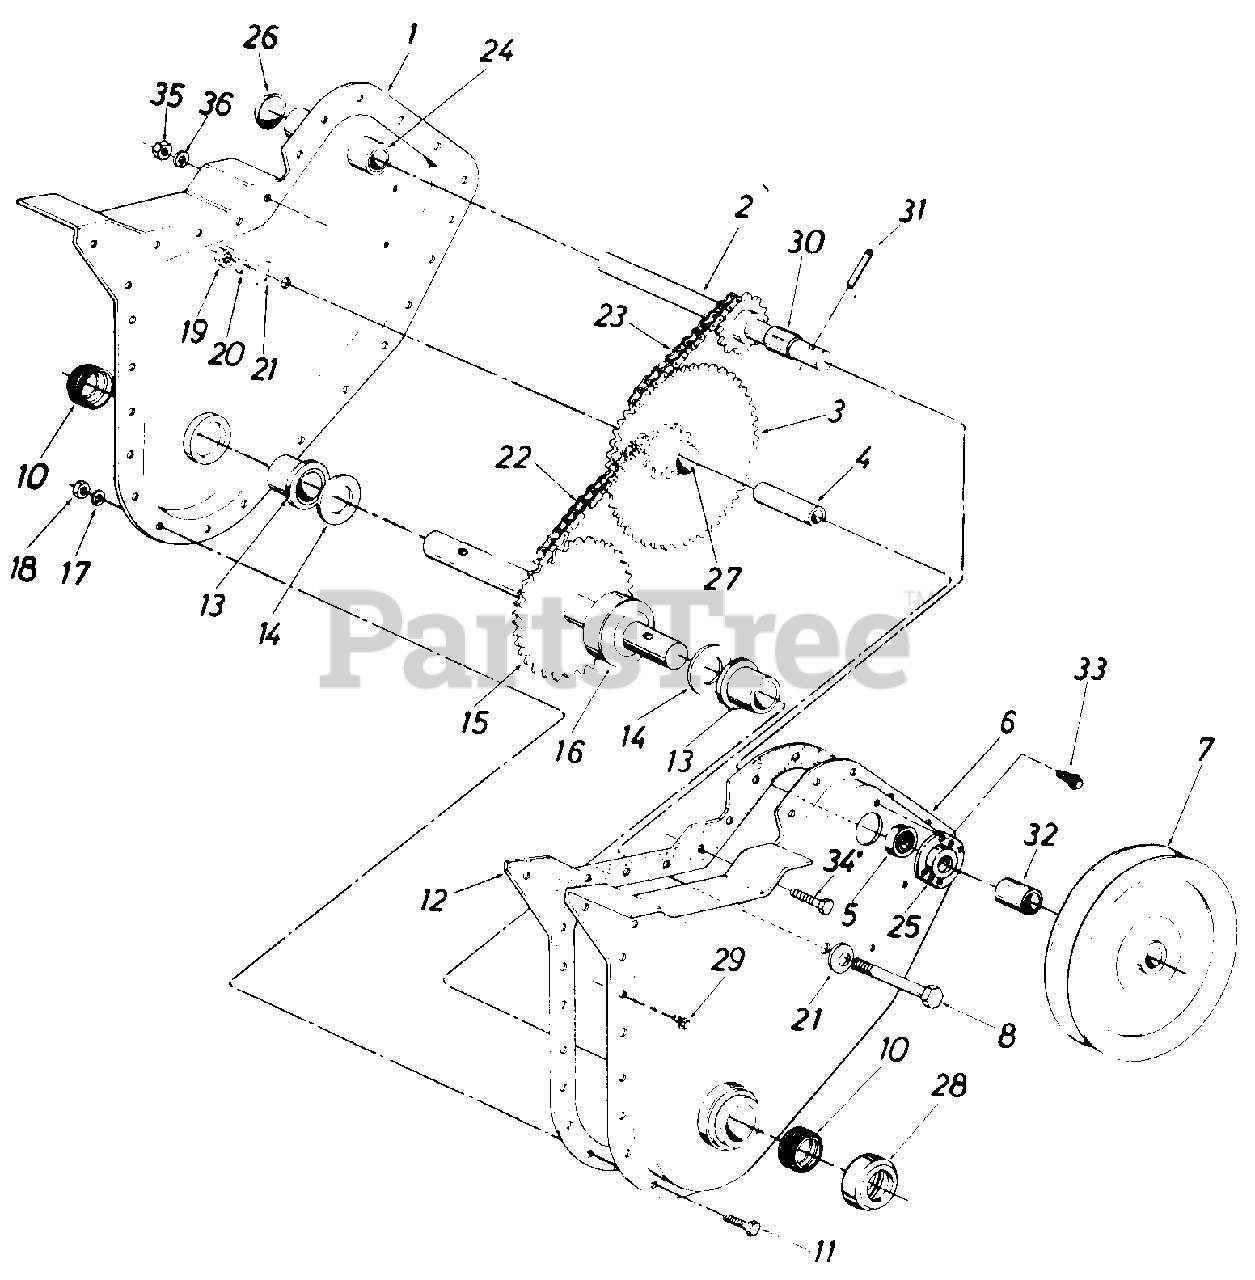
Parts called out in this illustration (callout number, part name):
1	Chain Case Ass'y. R.H.
2	Input Shaft Ass'y.
3	Hub and Sprocket Ass'y.
4	Bearing Inner Race
5	Ball Bearing
6	Chain Case Ass'y. L.H.
7	Pulley Chain Case 5-1/2 x 1/2
8	Hex Bolt 3/8-24 x 2.50" Lg.
11	Hex Bolt 1/4-28 x .625" Lg.
12	Gasket
13	Flange Brg. .879 I.D.
14	Fl-Wash. .88 I.D. x 1.50 O.D. x .030
15	Tine Shaft Ass'y.
16	Spacer 7/8" I.D. x 2.0" O.D. x .68" Lg.
17	L-Wash. 1/4" Scr.
18	Hex Nut 1/4-28 Thd.
19	Hex Ins. L-Nut 3/8-24 Thd.
20	L-Wash. 3/8" I.D.
21	Bell-Wash. .406 I.D.
22	Chain #420 .50" Pitch x 38 Links
23	Chain #35 .375" Pitch x 50 Links
24	Bearing .62" I.D. x .813 O.D. x 1.31
25	Bearing Housing
26	Expansion Plug 13/16" Dia.
27	Bearing
28	Dust Cap
29	Hex Wash. Hd. Self-Tap Scr. 1/4-20 x .50" Lg.
30	Spacer .630 I.D. x .38" Lg.
31	Spring Pin Spiral 1/4" Dia. x 1-1/2" Lg.
32	Spacer .647 x 1.25"
33	Hex Wash. Hd. Self-Tap Scr. 1/4-20 x .38" Lg.
34	Hex Bolt 5/16-18 x .75" Lg.
35	Hex Nut 5/1 6-18 Thd.
36	L-Wash. 5/16" I.D.
